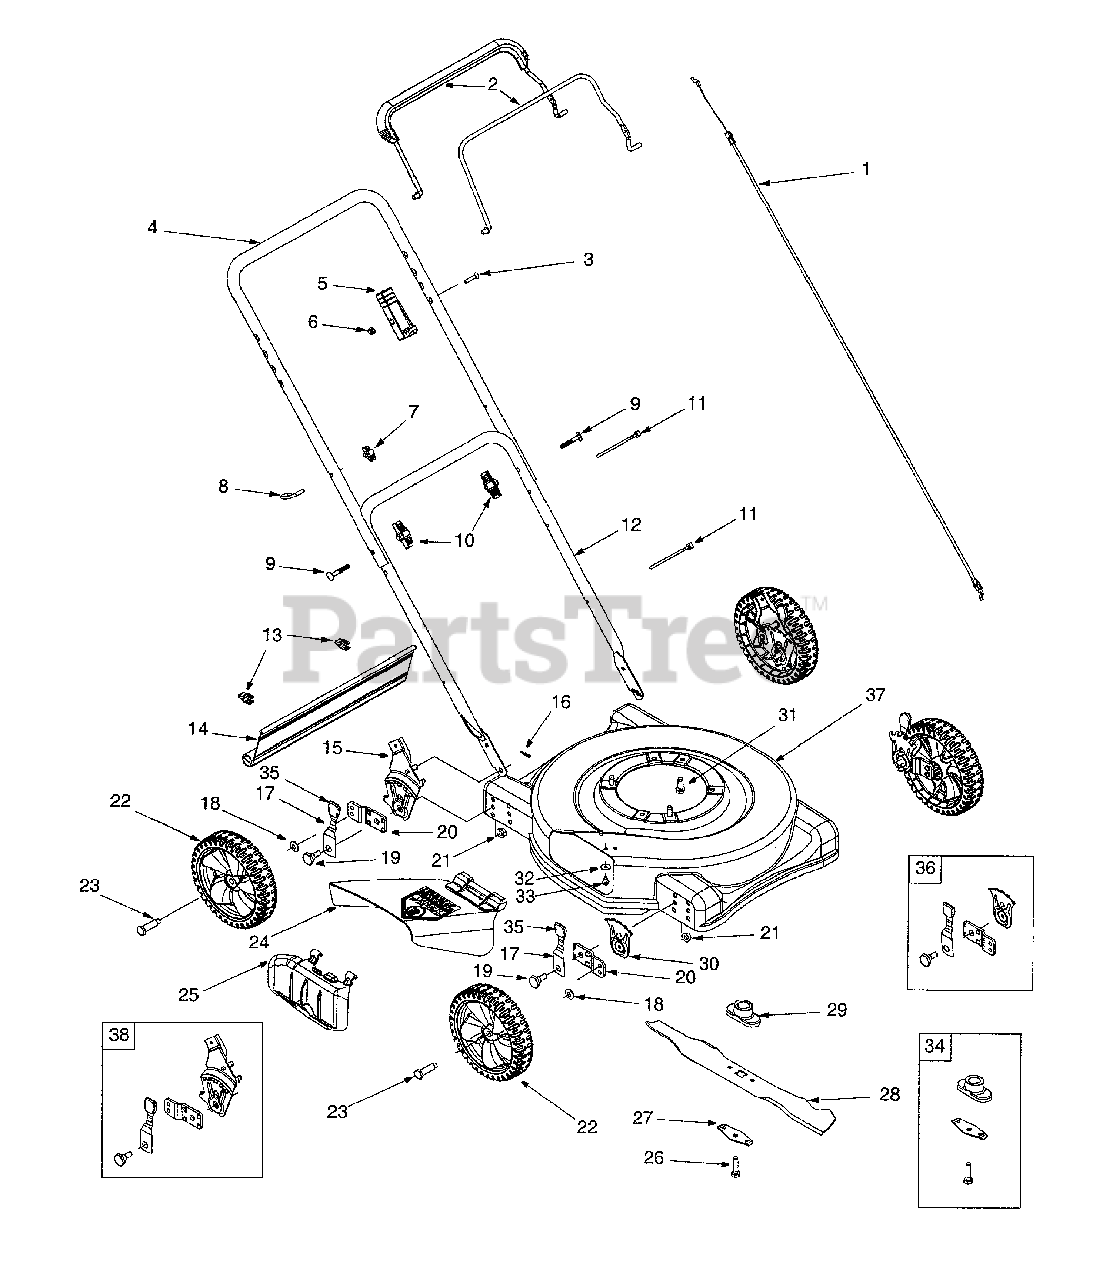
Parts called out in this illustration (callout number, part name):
1	Control Cable- 40.5"
3	Ocal C-sunk Machine Screw
5	Control Cable Housing
6	Hex Lock Nut, Nylon, 1/4-20 GR8
7	Wing Knob
8	Eye Bolt
9	Carriage Bolt
10	Wing Knob
11	Cable Tie
13	Hinge Clip
14	Rear Trail Shield
15	Height Adjustment Bracket, RH
16	Internal Cotter Pin
17	Spring Lever
18	Bell Washer, .400 ID x .88"
19	Shoulder Bolt, 1/2 x .357"
20	Wheel Pivot Bar
21	Flange Lock Nut, 3/8-16
22	Wheel Assembly
23	Shoulder Screw, .498 x 1.445: 3/8-16
24	Side Discharge Chute
25	Mulch Plug
26	Hex Head Cap Screw, 3/8-24 x 1.5 GR8
27	Blade Bell Support
28	Standard Blade
29	Blade Adapter w/Star
30	Height Adjustment Plate
31	Self Tapping Screw, 3/8-16 x 1"
32	Bell Washer
33	Self Tapping Screw, 1/4-20 x 1/2"
34	Blade Adapter Kit
35	Height Adjuster Knob
36	Height Adjuster Assembly, RH
